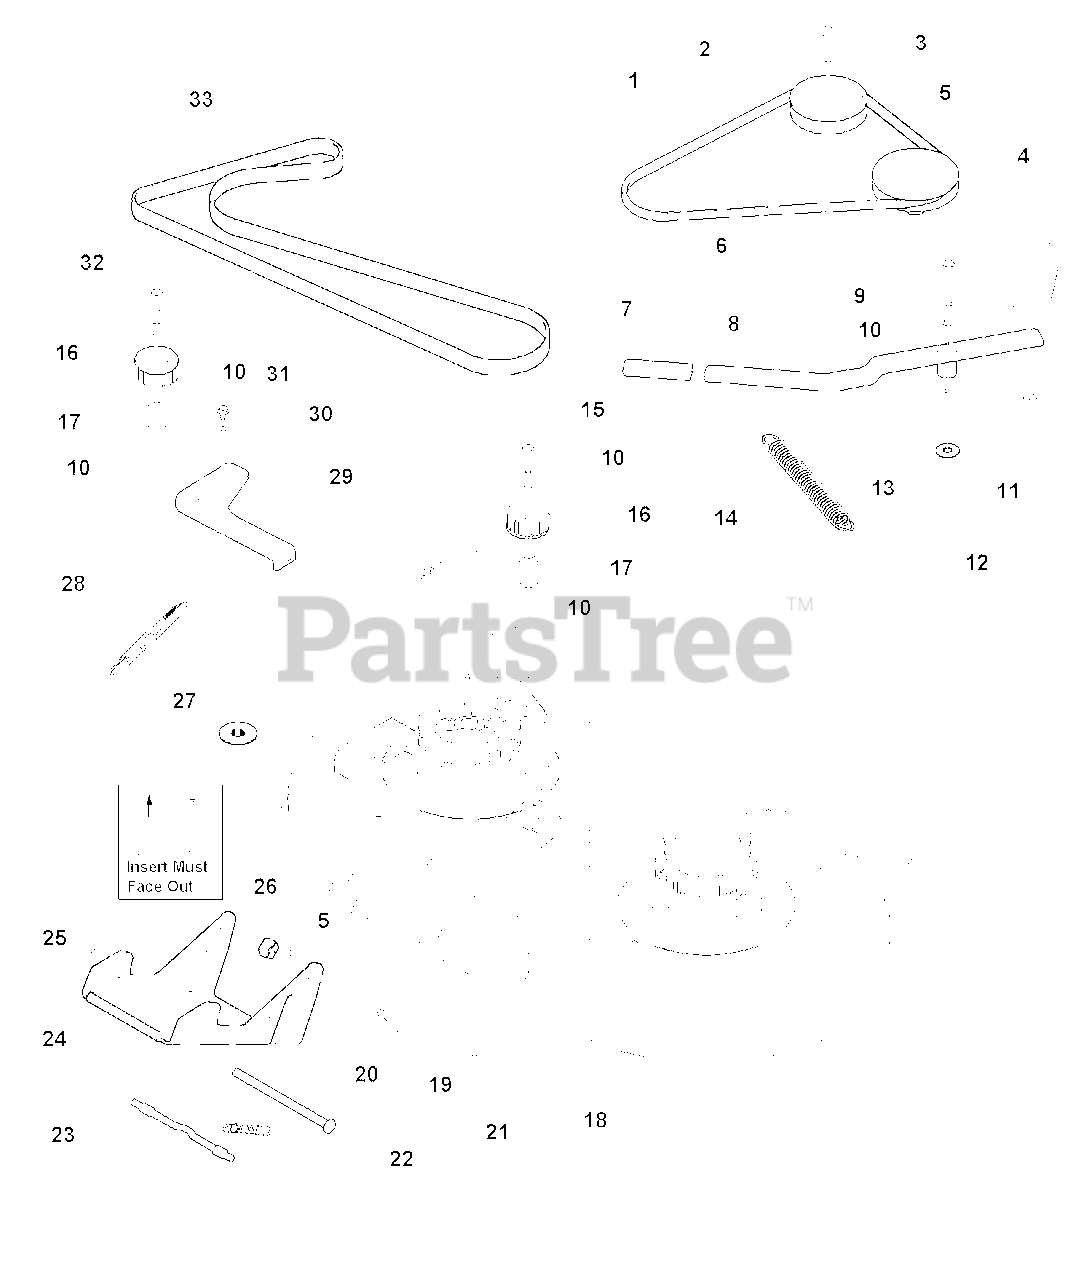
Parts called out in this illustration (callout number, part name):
1	V-BELT
2	PULLEY, 4-1/2 OD
3	NUT, Hex Lock ESNA, 3/8-16
4	PLATE ASEMBLY
5	WASHER
7	GRIP, Black
8	IDLER ARM ASSEMBLY, W/BUSHINGS
9	CAPSCREW, Hex Head, 3/8-16 x 3, G8
10	WASHER
11	CARRIAGE BOLT, 3/8-16 x 2-1/2
13	WASHER
14	SPRING, Extension
15	CAPSCREW, Hex Head, 3/8-16 x 1-3/4
16	PULLEY, Idler
18	NUT, Hex Flange Lock, 3/8-16
19	CAPSCREW, Hex Head, 3/8-16 1-1/2
22	SPRING, Extension
24	HITCH, Mower
25	NUT, Push
26	NUT, Hex Lock ALUM INSERT, 3/8-16
27	WASHER & LOCK NUT ASSEMBLY, 3/8-16
28	SPRING, Extension
29	ARM, Idle
31	SCREW, Hex Head Taptite, 5/16-18 x 5/8
32	CAPSCREW, Hex Head, 3/8-16 x 2
33	BELT, Timing
